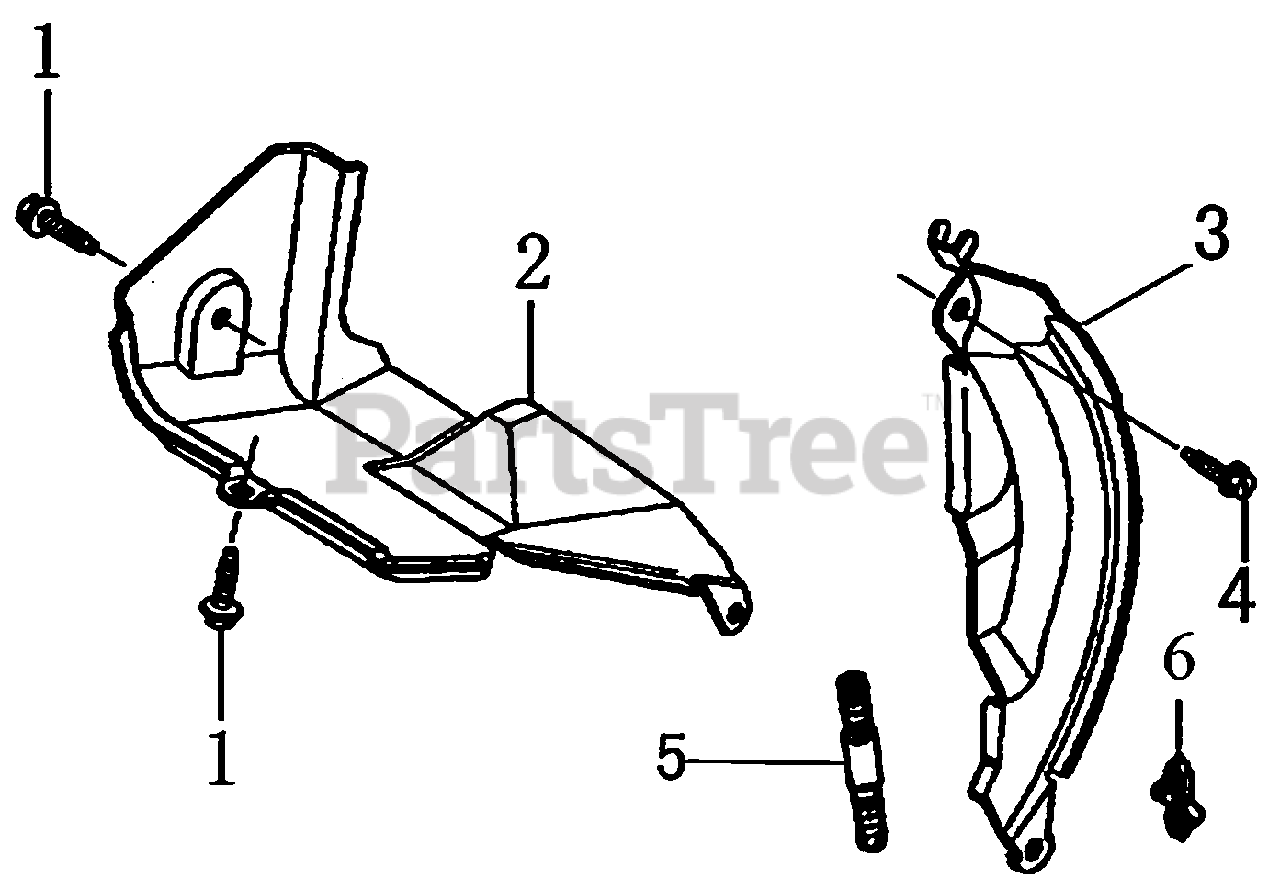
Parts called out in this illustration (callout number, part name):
1	BOLT, FLANGE
2	SHROUD COMP
3	PLATE, SIDE
4	BOLT, FLANGE
5	BOLT, STUD
6	CABLE CLIP
